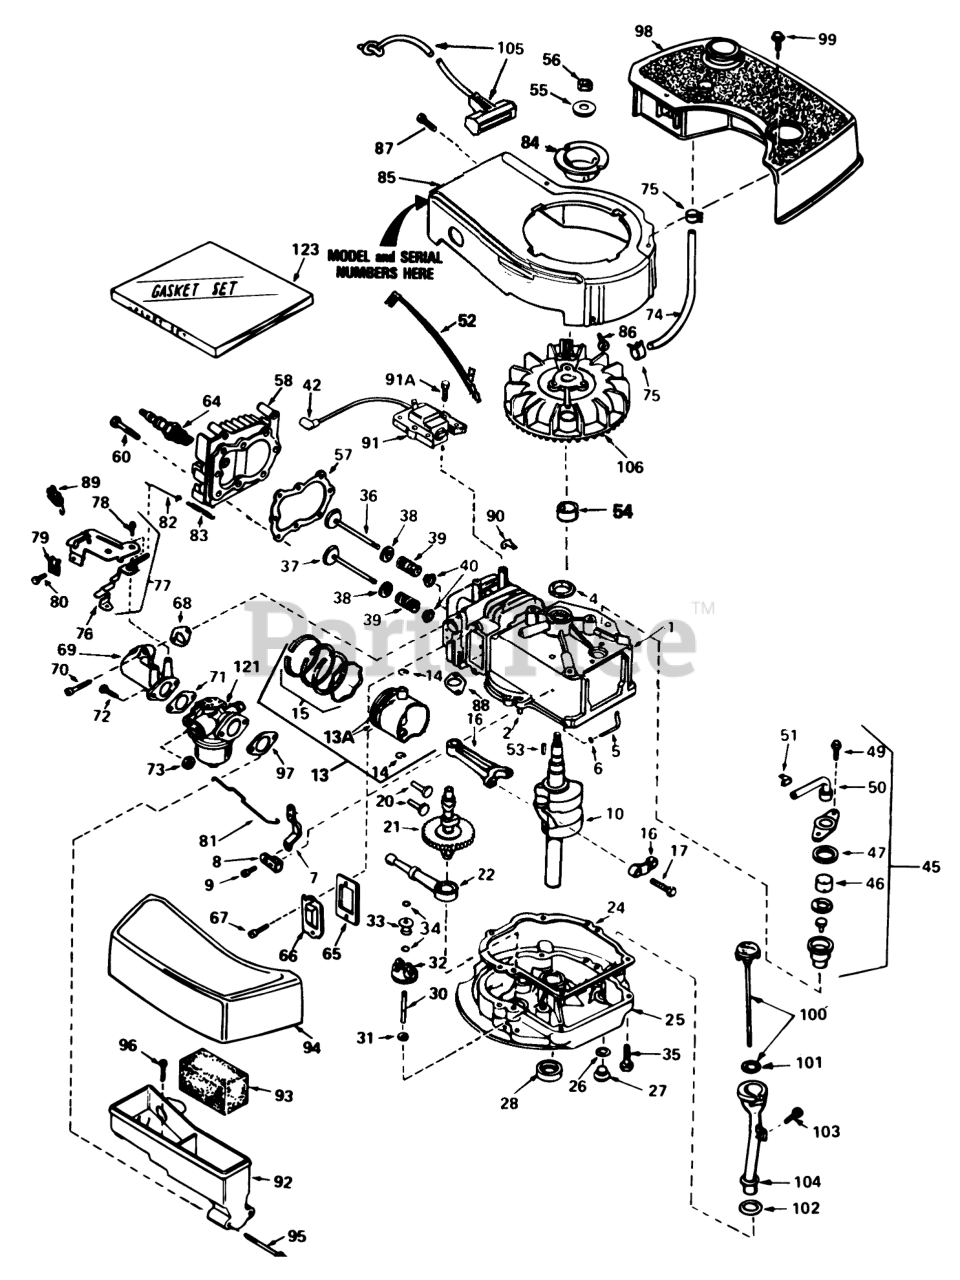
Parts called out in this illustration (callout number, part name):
1	Cylinder Assy (Incl. #2 & 4)
2	Pin-Dowel
4	Seal-Oil
5	Rod, Governor (Incl. Ref. #6)
6	Washer-Flat
7	Governor Lever
8	Clamp-Lever, Governor
9	Screw
10	Crankshaft
13	Piston, Pin & Ring Assy. (Std.)(Incl. Ref. #13A, 14 & 15)
13	Piston, Pin & Ring Assy. (.010 O.S.)(Incl. #13A, 14 & 15)
13	Piston, Pin & Ring Assy. (.020 O.S.)(Incl. #13A, 14 & 15)
13A	Piston & Pin Assy. (Std.)(Incl. Ref. #14)
13A	Piston & Pin Assy. (.010 O.S.)(Incl. Ref. #14)
13A	Piston & Pin Assy. (.020 O.S.)(Incl. Ref. #14)
14	Ring-Retaining, Piston Pin
15	Ring Set (Std.)
15	Ring Set (.020" OS)
15	Ring Set (.010" OS)
16	Rod Assy., Connecting (Incl. Ref. #17 )
17	Bolt-Rod, Connecting
20	Lifter-Valve
21	Camshaft(Mech.Comp. Release)
22	Oil Pump ASM
24	Gasket, Mounting
25	Flange Assy., Mounting (Incl. Ref. #26 thru 30)
26	Gasket-Oil Drain
27	Plug Oil Drain
28	Seal Oil
30	Shaft-Governor
31	Washer-Flat
32	Gear Assy., Governor (Incl. Ref. #31 )
33	Spool-Governor
34	Ring-Retaining
35	Screw (1/4-20 x 1-1/4)
36	Valve, Intake (Std.)(Incl. Ref. #40)
36	Valve, Intake (1/32" O.S.)(Incl. Ref. #40)
37	Valve, Exhaust (Std.)(Incl. Ref. #40)
37	Valve, Exhaust (1/32" O.S.)(Incl. Ref. #40)
38	Cap-Upper Valve Spring
39	Spring-Valve
40	Cap-Valve, Spring
42	Cover-Spark Plug
45	Breather Assy. (Incl. #46-51 )
46	Element-Breather
47	Gasket-Breather
49	Screw (10-24 x 9/16)
50	Tube, Breaker
51	Clip, Breather Tube
52	Wire-Ground
53	Key-Flywheel
55	Washer-Belleville
56	Nut-Flywheel
57	63573 GIL 42 SNWTHW
58	Head-Cylinder
60	Screw (5/16-18x1-1/2)
64	Plug, Spark (J17LM or equiv.)
64	Plug, Spark (Champion RCJ-8)
65	Gasket-Breather
66	Cover-Valve
68	Gasket-Intake
69	Pipe, Intake (Incl. Ref. #68)
70	Screw (1/4-20 x 1)
71	Gasket-Carburetor
72	Screw (1/4-28 x 7/8)
73	Nut and Lock Washer (1/4-28)
74	Line-Fuel
75	Clamp-Line, Fuel
76	Lever Control
77	Control Assy., Speed (Incl. Ref. #76, 78 & 89)
78	Screw, Hex Washer Hd Shoulder Self-Tap
79	Conduit
80	Screw (10-32 x 3/8)
81	Link-Throttle
82	Link Governor Spring
83	Spring Governor
84	Hub-Starter
85	Housing Blower
86	Screw (1/4-20x19/32)
87	Screw (10-24 x 9/16)
88	Gasket Exhaust
89	Terminal
90	Clip-Wire
91	Lamination & Coil Assy. (Solid State)(Incl. Ref. #42)
91A	Screw
92	Body Air Cleaner
93	Filer, Air
94	Cove, Air Cleaner
95	Screw Fil Hd.
96	Screw, Hex Hd.
97	Gasket-Air Cleaner
98	Tank-Fuel
99	Screw (10-32 x 35/64)
100	Dipstick, Oil (Incl. Ref. #101)
103	Screw (10-32 x 1/2)
104	Tube-Oil Fill
105	Rope Assy., Starter
106	Flywheel
121	Carburetor (Incl. Ref. #71 )
123	Gasket Set
